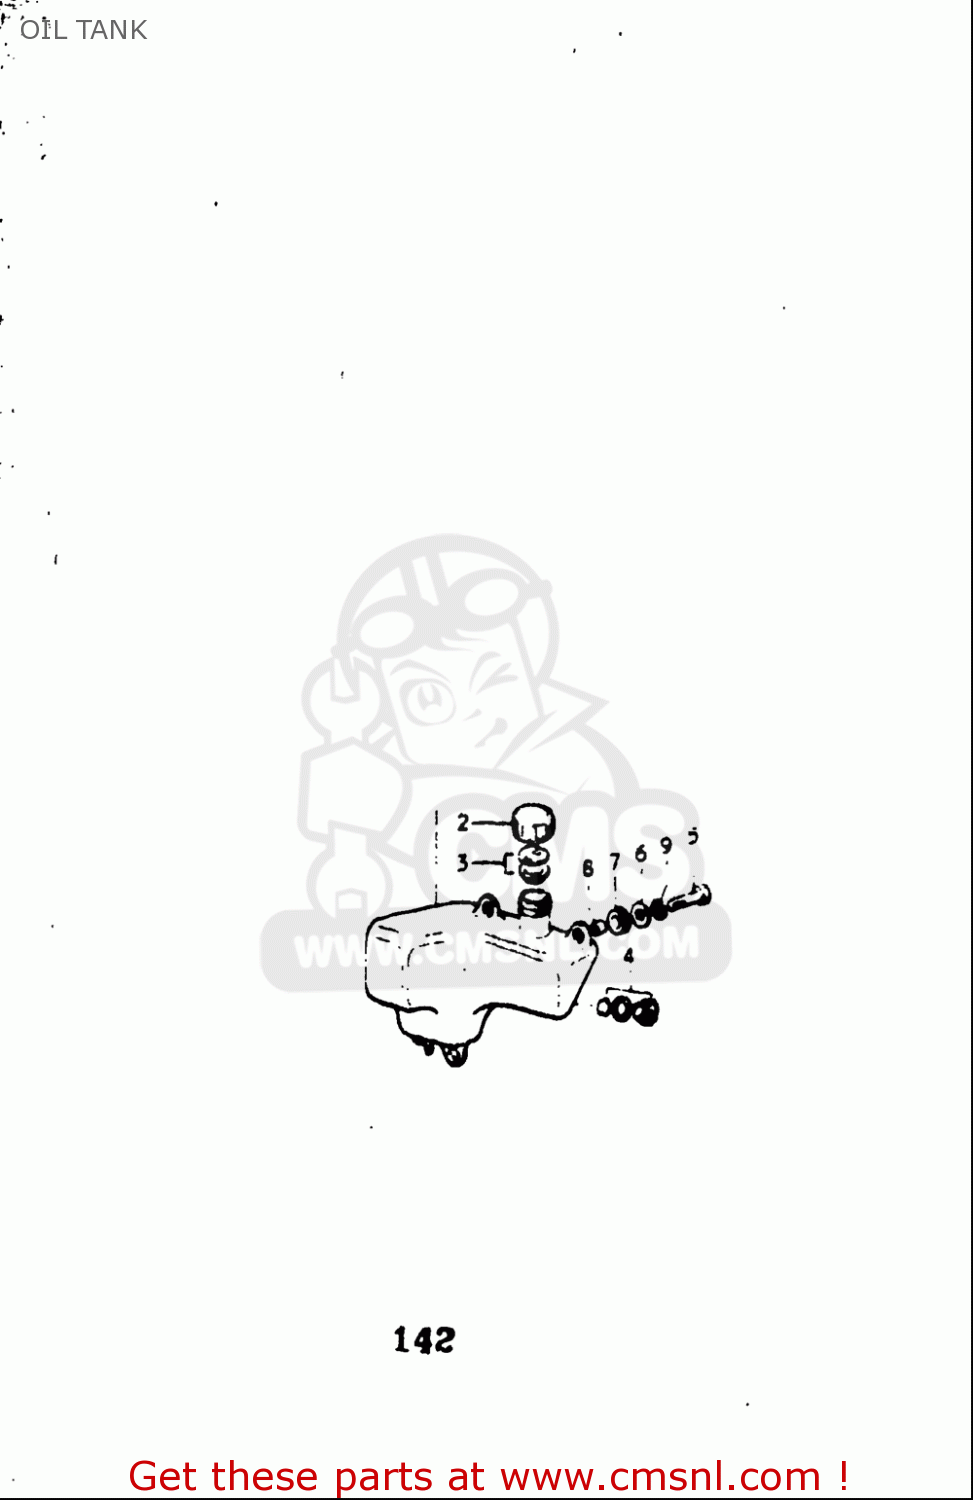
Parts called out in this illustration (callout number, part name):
2	CAP,OIL TANK
3	GASKET SET (NAS)
4	LENS SET,OIL LEVEL
5	BOLT
6	WASHER(6.5X18X1.6)
7	CUSHION
8	SPACER(6.5X10X10)
9	WASHER,LOCK
